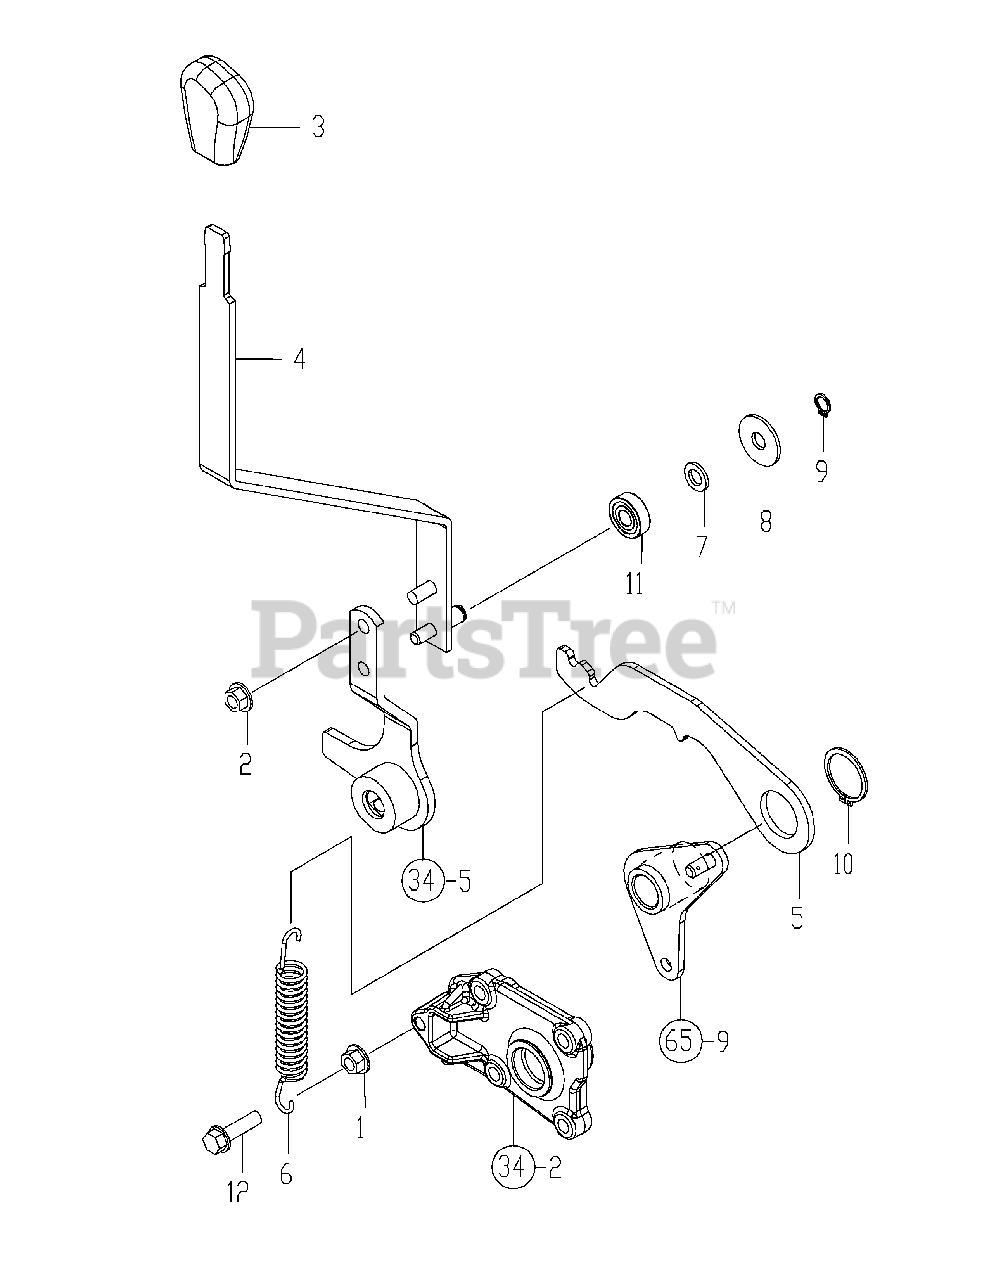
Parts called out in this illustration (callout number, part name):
3	KNOB, ORANGE
4	LEVER CMP, RANGE
11	BEARING, 6000UU
